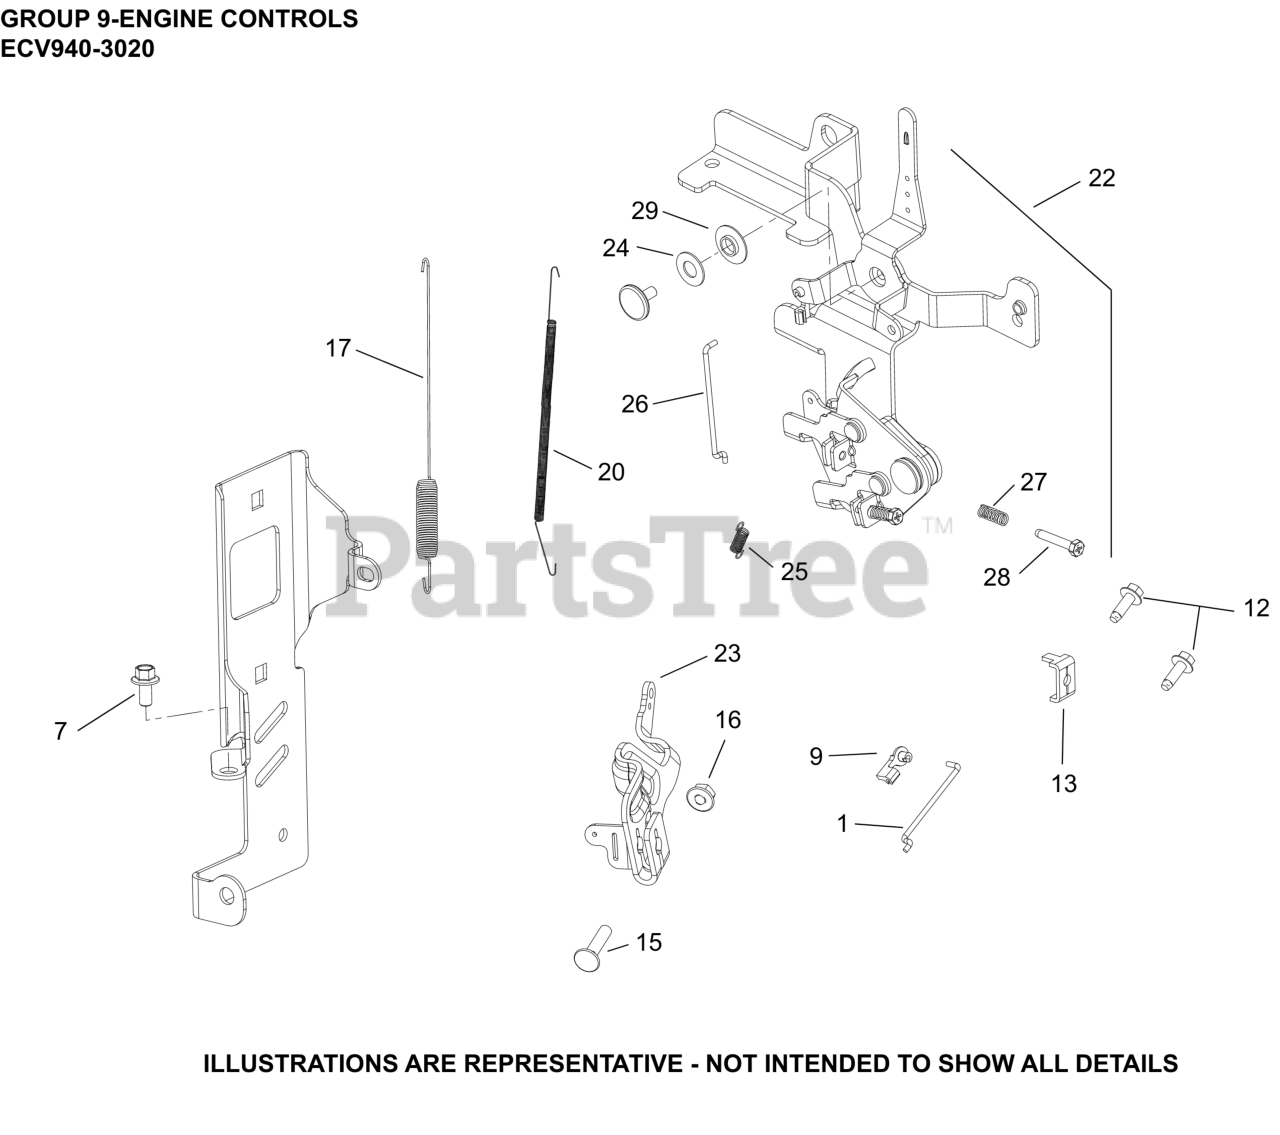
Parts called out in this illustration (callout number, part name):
1	LINKAGE, THROTTLE EFI, VERTICAL
7	SCREW, FLG M6X1.0X12
9	BUSHING, THROTTLE LINKAGE
12	SCREW, THREAD FORMING
13	CLAMP, CABLE CABLE
15	BOLT, RD HD SQ NECK M6X1.0X25
16	NUT, FLG M6X1.0
17	SPRING, GOV (IDLE 1400-1625)
17	SPRING, GOVERNOR
20	SPRING, LINKAGE
22	CONTROL ASSY SPEED (VERTICAL) EFI
23	KIT, GOVERNOR LEVER
24	WASHER, FLAT 9 MM
25	SPRING, RETURN
26	LINKAGE, THROTTLE LEVER
27	SPRING, SPEED CONTROL (SHORT)
28	SCREW, PHL THD FRM M4X0.7X25
29	WASHER, NYLON SHOULDER
